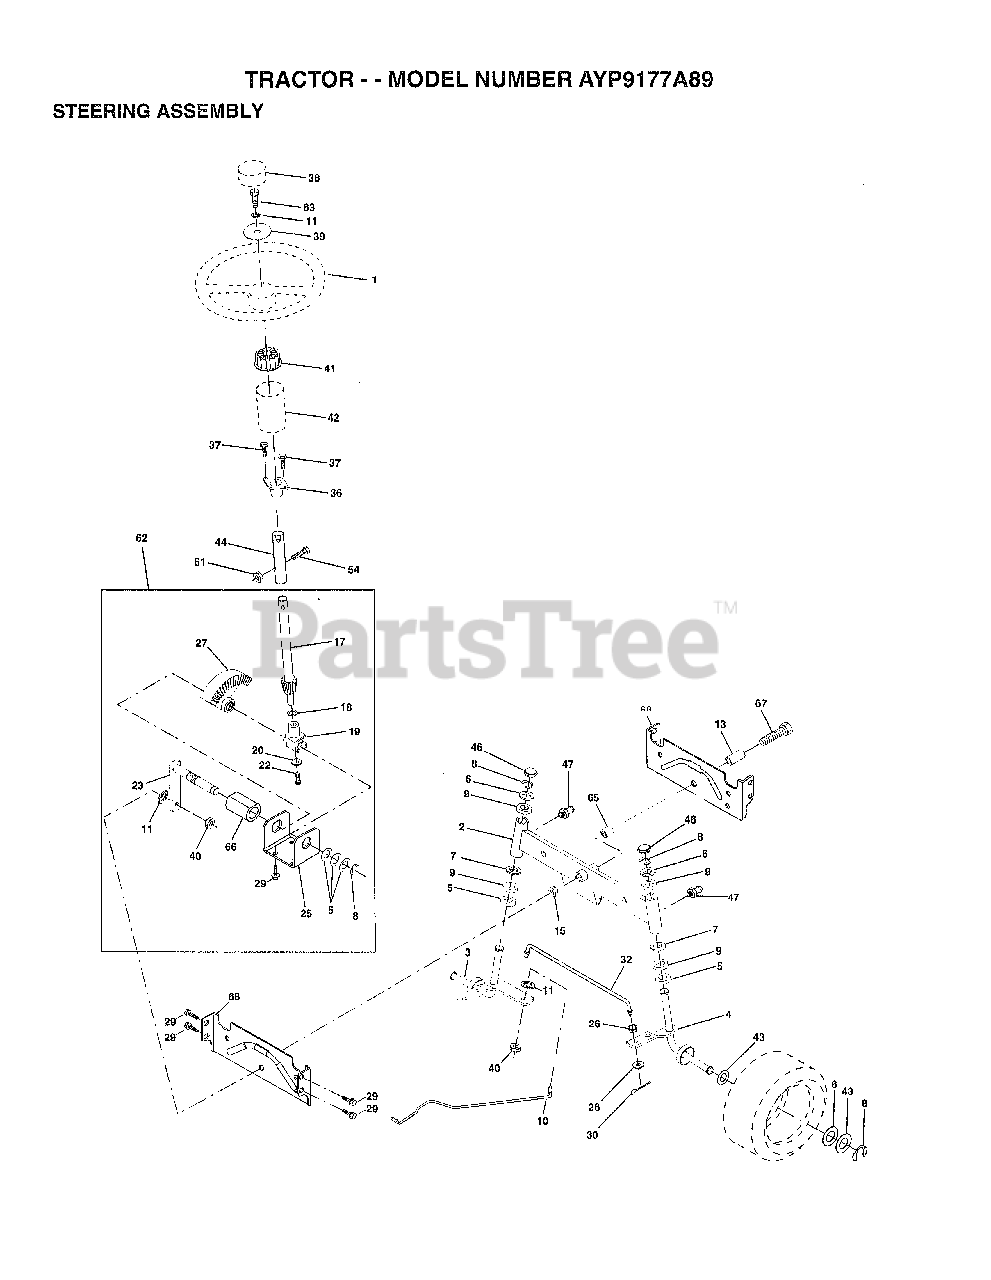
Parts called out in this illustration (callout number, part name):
1	WHEEL STR AYP BLK
2	AXLE ASM
3	SPINDLE.ASM.LH
4	"SPINDLE ASM,RH"
5	WASHER .T
6	WASHER
7	WASHER
8	RING
9	COL. SRTG. BEAR.
10	DRAGLINK-STAMPED
11	LOCKWASHER
13	BEARING AXLE
15	"NUT-LOC,FLANGE LT"
17	SHAFT ASM STEERIN
18	THRUST WASHER
19	SUPPORT.SHAFT
22	SCREW HEX SOC1/4-
25	BRKT-STEERING
26	BUSHING.DRAGLINK
27	GEAR SECTOR
28	WASHER
29	SCREW
30	COTTER PIN
32	TIE ROD
36	BUSHING.STEERING
37	"SCREW-TT,10-32 FL"
38	CAP STEER AYP
39	WASHER T
40	GRIPCO NUT
41	ADAPTER LT
42	BOOT.STEER.PL
44	EXT SHAFT STEERIN
46	CAP
47	ZERK M
51	NUT
54	BOLT
62	KIT STEERING ASM
63	BOLT
65	SPACER AXLE
66	"BEARING-ARM,PITMA"
67	BOLT
68	BRACE AXLE
